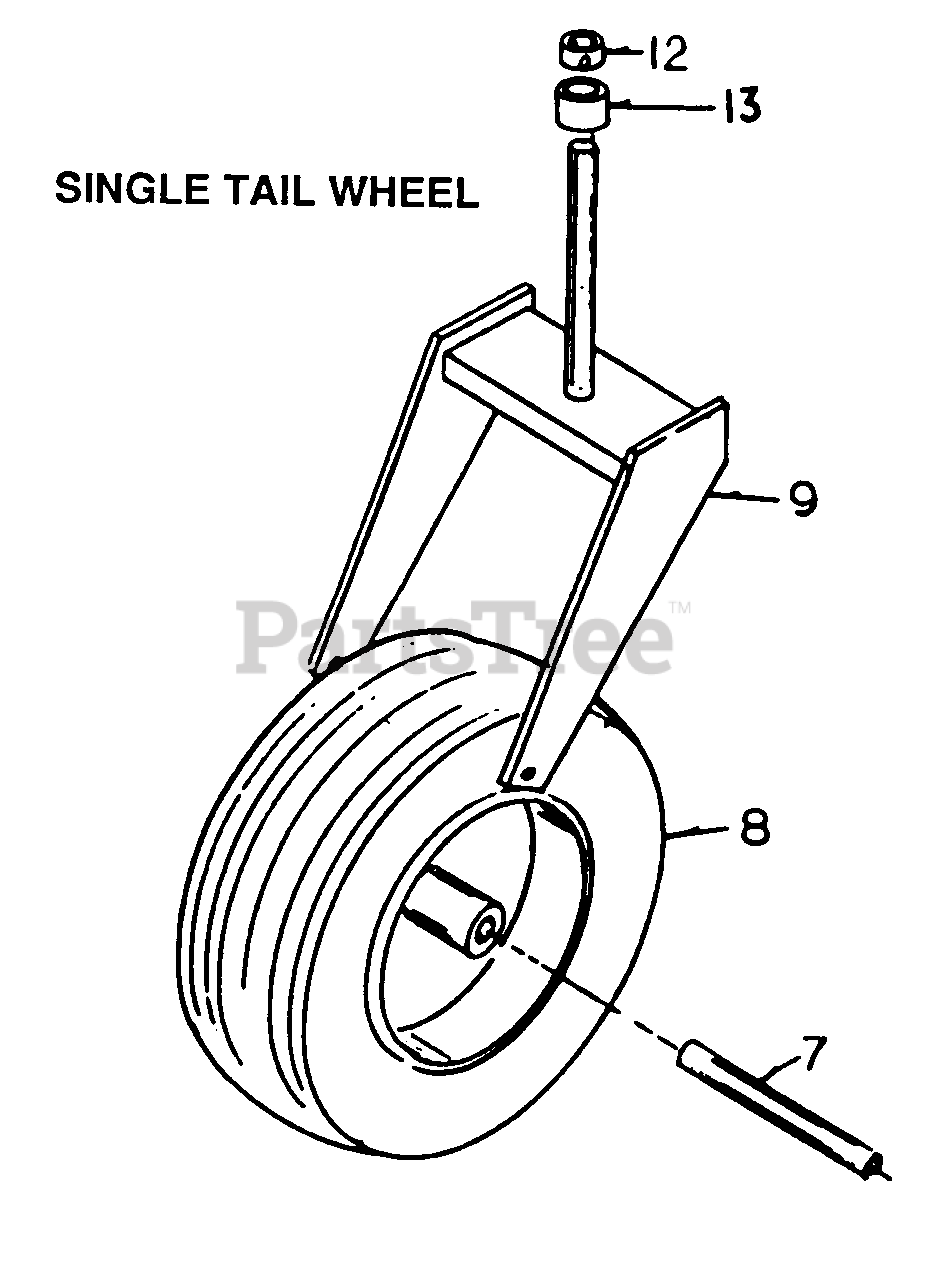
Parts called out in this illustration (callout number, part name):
8	Tail Wheel Assembly
9	Tail Wheel Fork
12	Set Collar, 1"
13	Spacer, Tail Wheel Fork
